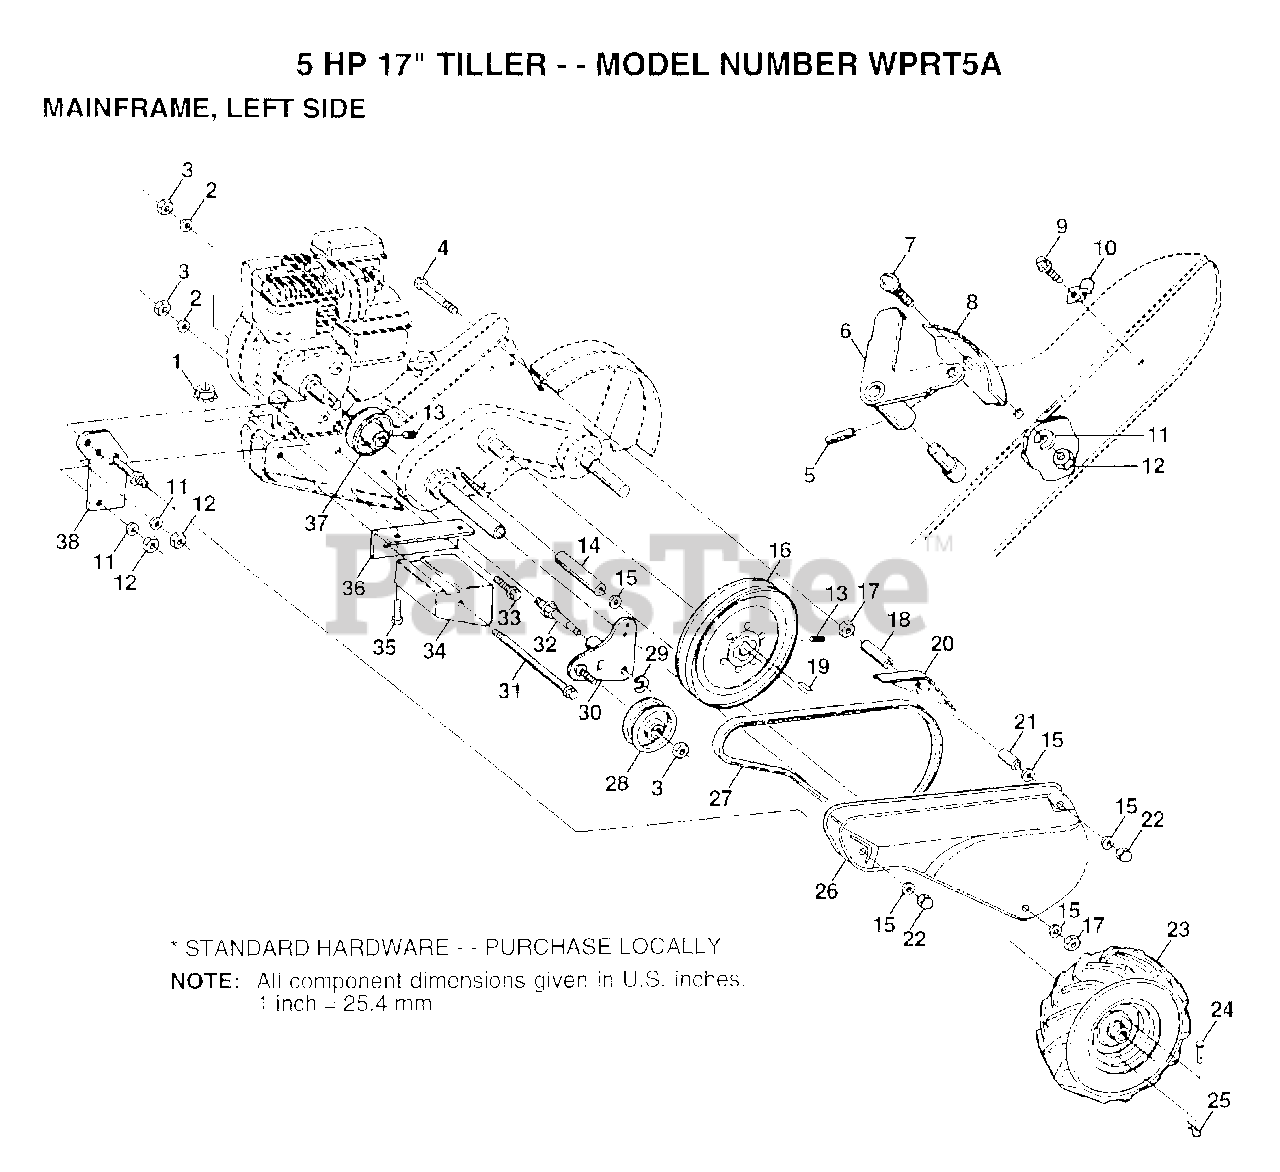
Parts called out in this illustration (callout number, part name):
2	LOCKWASHER
3	NUT.HEX.3/8-16UNC
4	BOLT TI
6	LEVER ASM CRT
7	BOLT
8	PANEL TI
10	CONDIUT CLIP T
11	LOCKWASHER
13	SET SCREW
14	SPACER
15	WASHER
16	"SHEAVE 10"" CRT"
17	NUT.HEX.5/16-18
18	SPACER CRT
19	KEY T
20	GUARD CRT
21	SPLIT SPACER
22	NUT TI
23	TIRE.CHV.13X5.0-6
24	RIVET.DRILL.1.75
25	RETAINER M
27	BELT-V
28	PULLEY-IDLER TI
29	KLIP RING
31	BOLT CRT
32	SHIFT ARM CRT
33	BOLT
34	COUNTERWEIGHT CRT
35	BOLT.HEX.5/16-1.5
36	BRACKET LH CRT
37	ENGINE SHEAVE
38	BELT GUARD BRKT
